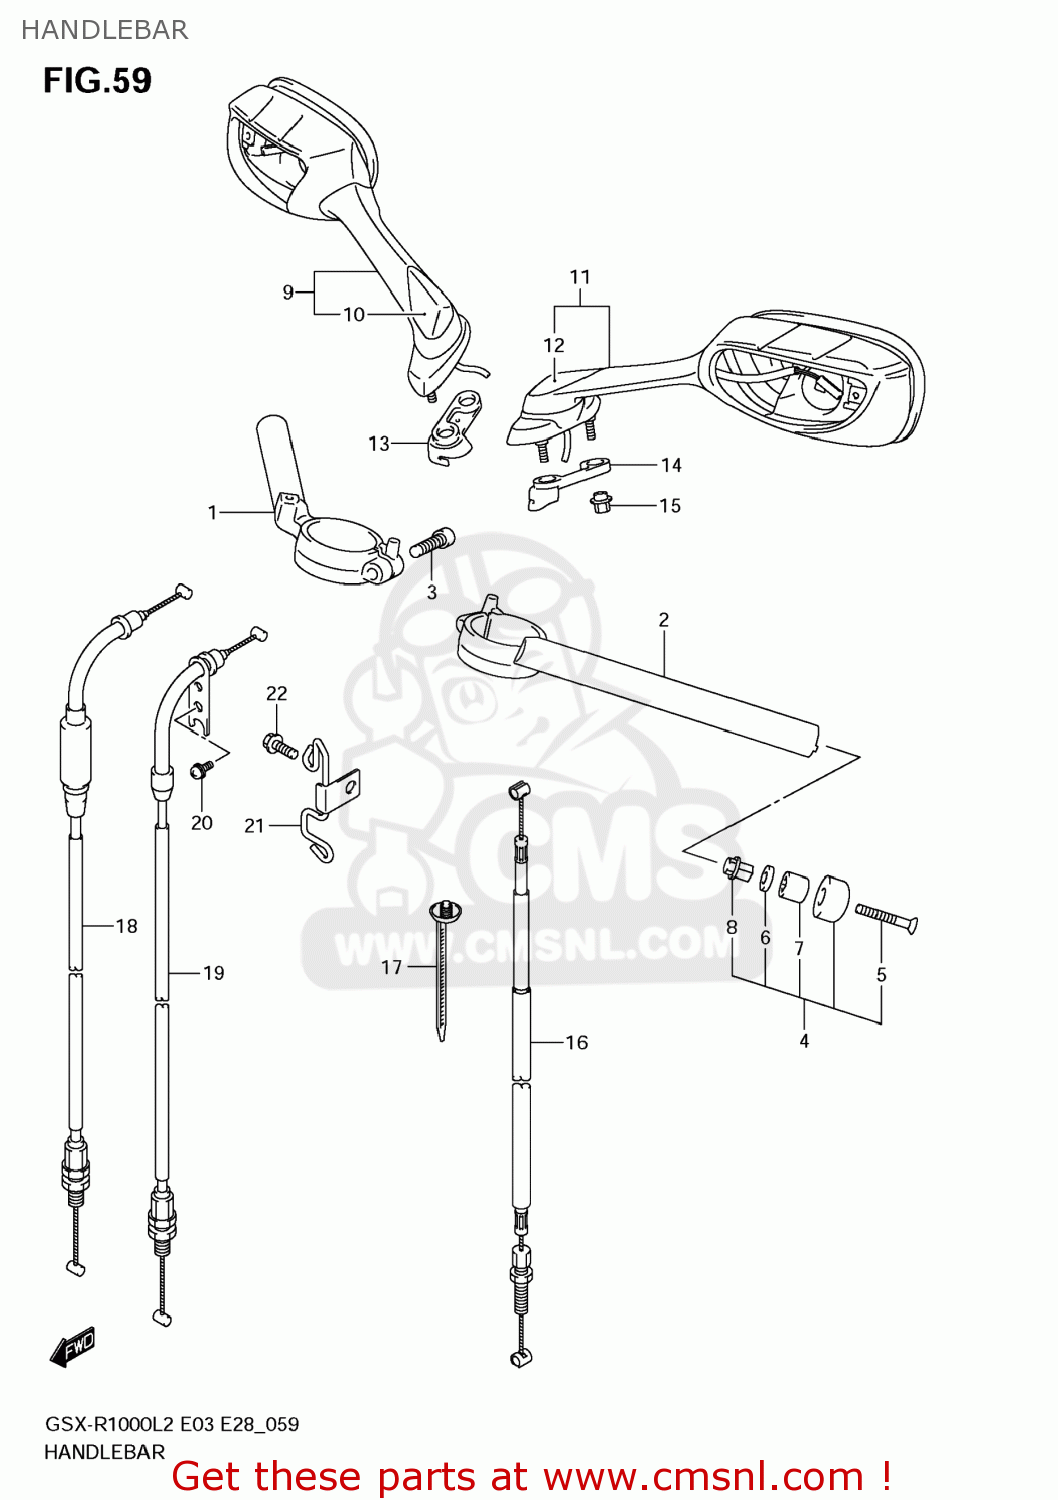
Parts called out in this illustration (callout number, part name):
1	HANDLEBAR,R
2	HANDLEBAR,L
3	BOLT(8X32)
4	BALANCER SET,HANDLEBAR
5	SCREW
6	WASHER(6.5X16X4)
7	EXPANDER,HANDLE BALANCER
8	NUT,HANDLE BALANCER
9	MIRROR ASSY,RR VIEW,R
10	CAP,R
11	MIRROR ASSY,RR VIEW,L
12	CAP,L
13	CUSHION,RR VIEW MIRRROR,R
14	CUSHION,RR VIEW MIRRROR,L
15	NUT,RR VIEW MIRROR
16	CABLE ASSY,CLUTCH
17	CLAMP(L:154)
18	CABLE ASSY,THROTTLE NO.1
19	CABLE ASSY,THROTTLE NO.2
20	SCREW(5X10)
21	GUIDE,CABLE
22	BOLT
